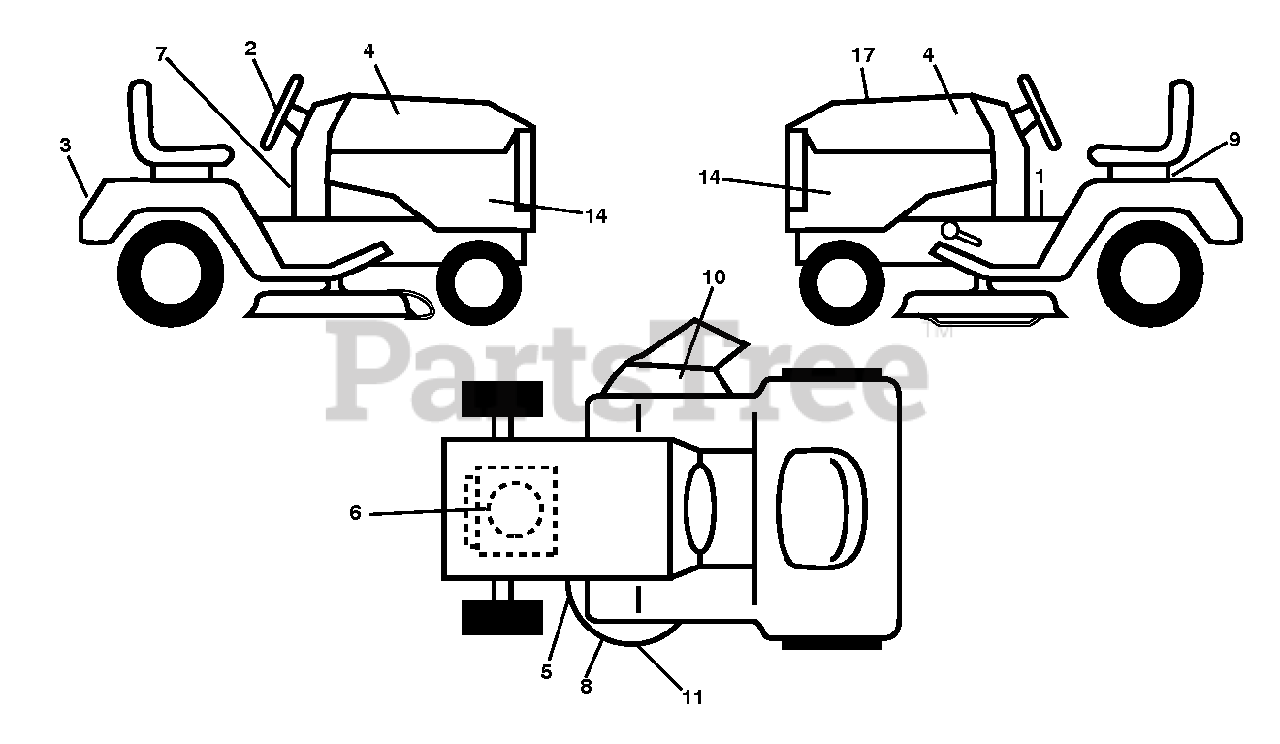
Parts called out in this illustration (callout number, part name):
1	DECAL.FENDER.WARNING.ENGLISH
2	DECAL.STRWHL.STDSQ.PPRO.BLK09
3	Decal, REARFNDR Logo BLK 2017
4	DECAL.POULAN PRO.YEL/BLK.2017
5	DECAL.MOWER.SCH.48/54.PREM
6	DECAL DECAL.ENG.B&S.20HP.INTEK
7	DECAL.DASH.SNOWFLAKE.BLACK.SM
8	DECAL.MOWER.CAUTION.TENSION.AR
9	DECAL BTRY SYMBOLS
10	DECAL, DECK DEFLECTOR, WARNING
11	DECAL.PPRO.10YRDECKWAR.POP
14	DECAL.SDPNL.PP22VA48.BLK.PPRO
17	DECAL.RPL.BSM44.TLW.48.GENTR
